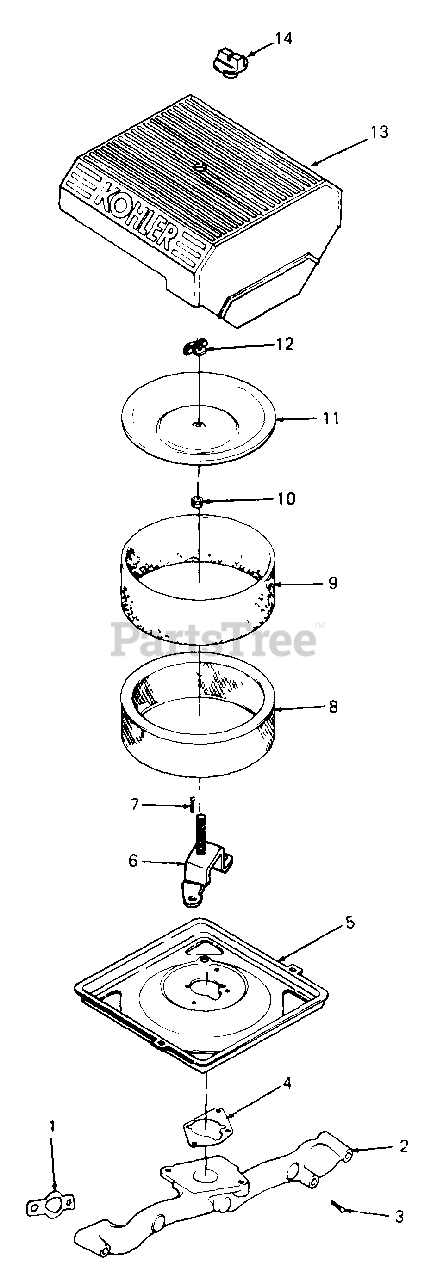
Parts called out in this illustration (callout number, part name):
1	Gasket, Intake Manifold
2	Manifold, Intake
3	Screw, M6 x 1.0 x 18
4	Gasket, Air Cleaner Base
5	Base, Air Cleaner
6	Bracket, Air Cleaner
7	Screw, M6 x 1.0 x 10
8	Element, Air Cleaner
9	Element, Pre-Cleaner
10	Seal, Air Intake
11	Cover, Inner Air Cleaner
13	Cover, Air Cleaner
14	Knob, Cover
